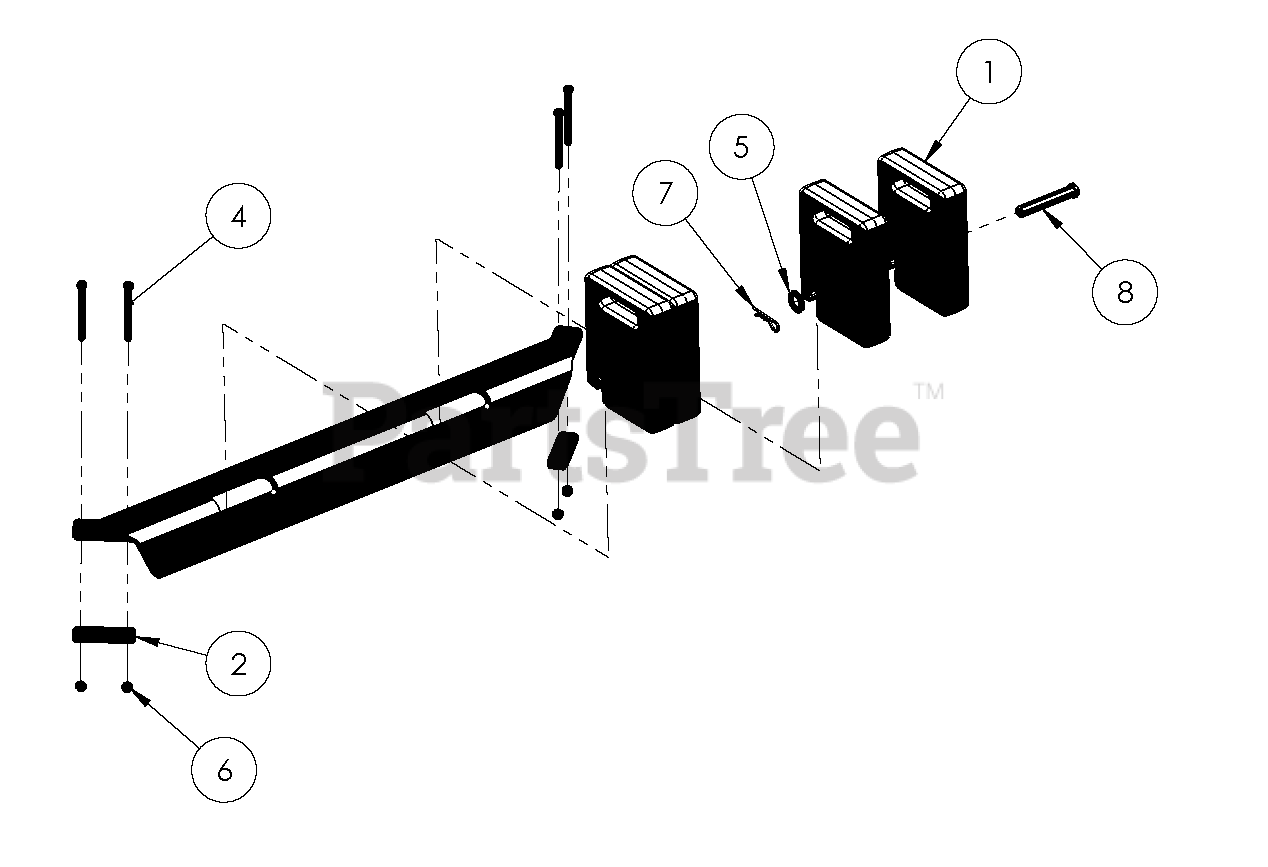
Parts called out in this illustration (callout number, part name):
1	Weight-Cast 28LB Front
2	Plate, Front Weight Frame
3	Bracket, Front WT FM 4-WT
4	BLT-HEX .38-16X4.00 GR5 YWZC
5	WSHR-FL-STL.812X1.50X.135YWCZ
6	Nut-LK-FLG .375-16 PL
7	1/8" Hair Pin
8	Pin, Clevis 3/4 X 4 1/2 Y
